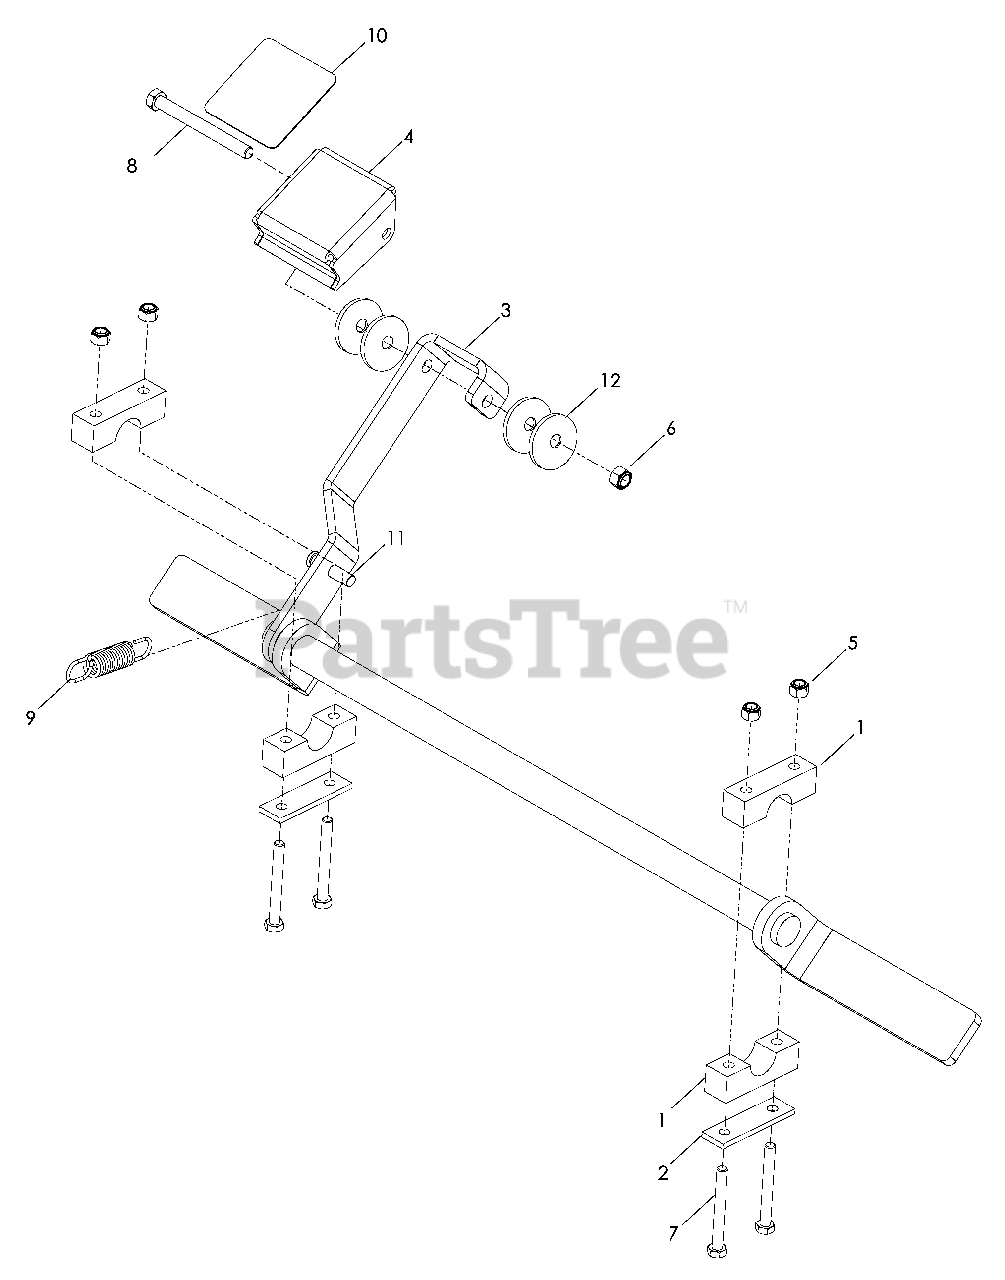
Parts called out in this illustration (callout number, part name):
1	PILLOW BLOCK
2	REINFORCEMENT BAR
3	PARK BRAKE
5	NUT 5/16-18 HEX NYLOC
6	NUT 3/8-16 HEX NYLOC
7	HCS 5/16-18 x 2¾
8	HCS 3/8-16 x 3¾
9	SPRING, EXTENSION
10	PAD, ANTI-SKID
11	PIN, CLEVIS 3/8 x 1½
12	WASHER, FRICTION
